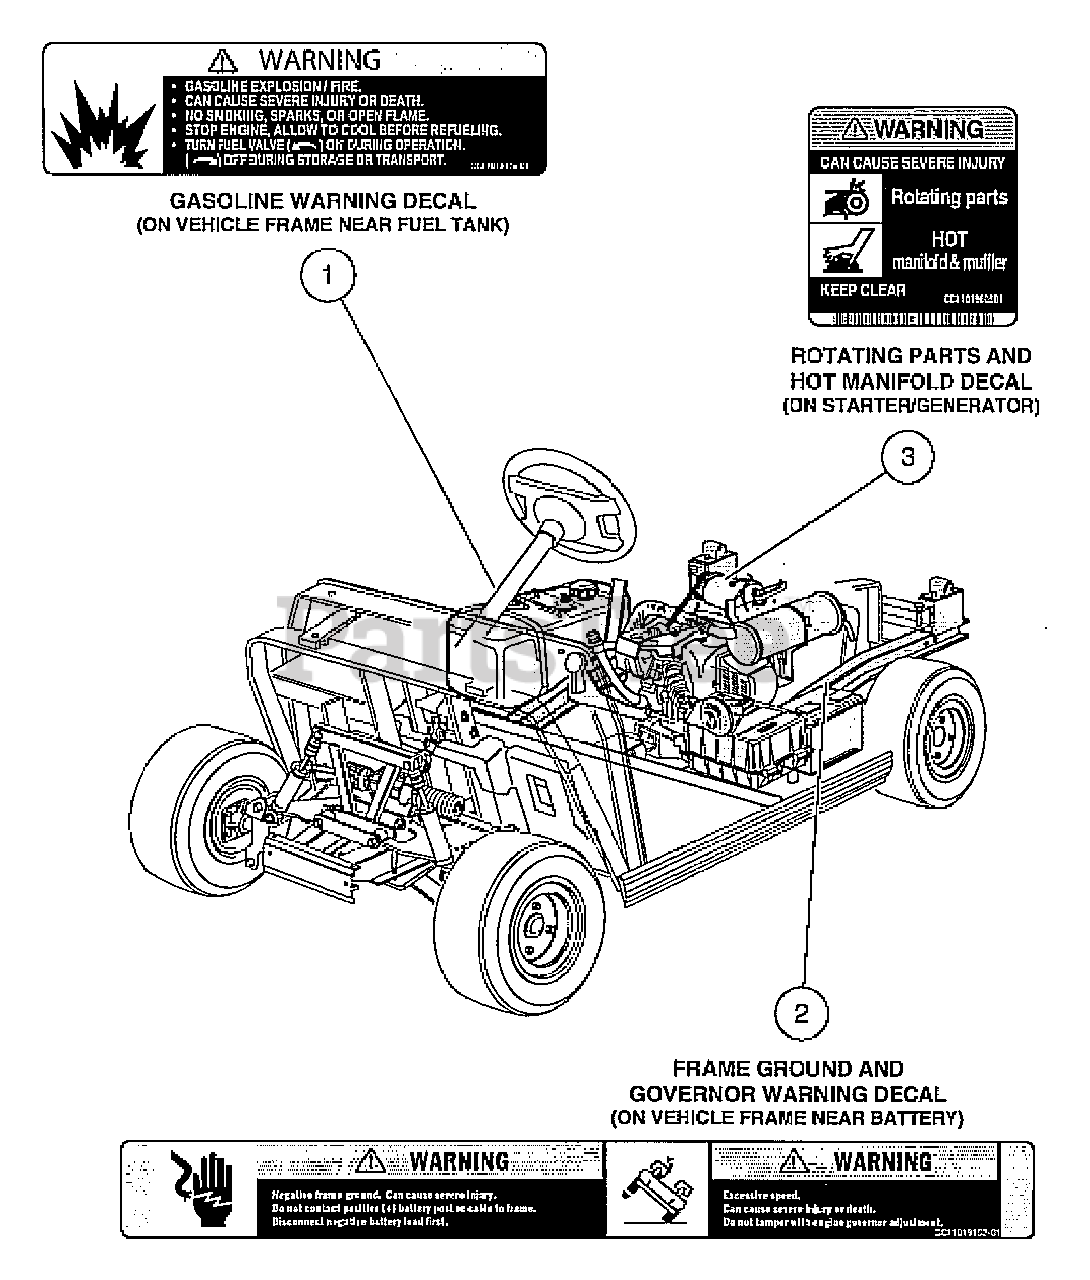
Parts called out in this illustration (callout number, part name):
1	Decal, Gasoline Explosion/Fire Warning
2	Decal, Frame Ground and Governor Warning
3	Decal, Rotating Parts/Mot Manifold
